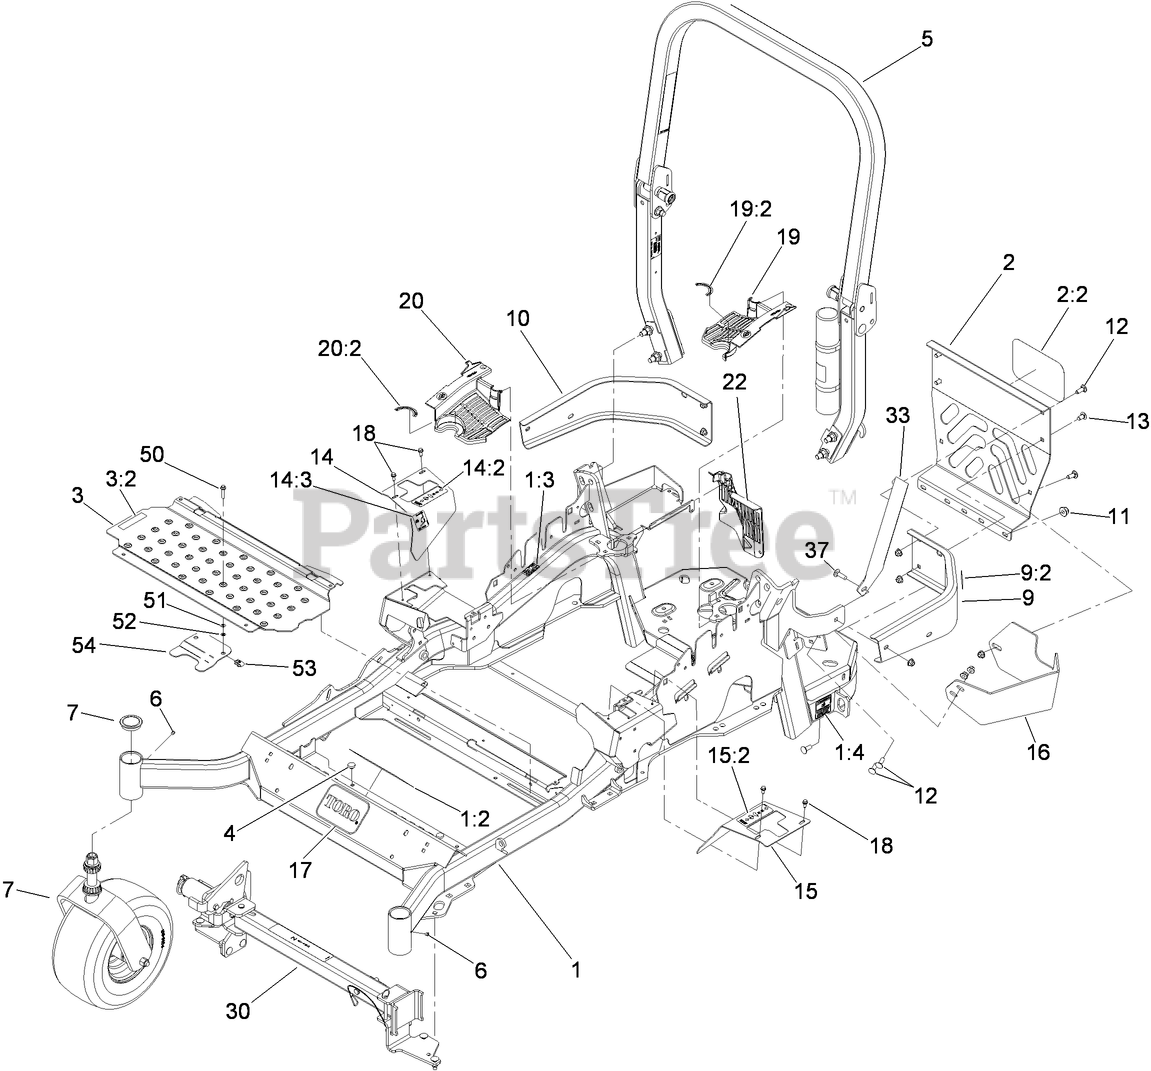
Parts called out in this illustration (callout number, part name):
1	MAIN FRAME ASM
1:2	DECAL-DANGER SLOPE W/ROPS
1:3	DECAL-WARNING
1:4	DECAL-HAZARD, PINCHED FINGER
2	REAR GUARD ASM
2:2	DECAL
3	FLOORPAN ASM
3:2	DECAL-MISSING, COVER
4	BUMPER
5	ROPS ASM
7	Caster Wheel ASM
9	LH REAR BUMPER ASM
9:2	DECAL-WARNING
10	BUMPER-RH
11	NUT-HF, NI
12	SCREW-CARR
13	SCREW-CARR
14	RH MOTION CONTROL COVER ASM
14:2	DECAL-CONTROL, MOTION
14:3	DECAL-PARKING BRAKE
15	LH MOTION CONTROL COVER ASM
15:2	DECAL-CONTROL, MOTION
16	GUARD-MUFFLER
17	DECAL
18	SCREW-HWH
19	LH HYDRO GUARD ASM
19:2	DECAL-HYDRO OIL
20	RH HYDRO GUARD ASM
20:2	DECAL-HYDRO OIL
22	GUARD-HYDRO, REAR (RH)
30	Z STAND ASM
37	BOLT-CARR
50	SCREW-HHF
51	WASHER-FLAT
52	NUT-RETAINER
54	ADAPTER-CAPTIVE
